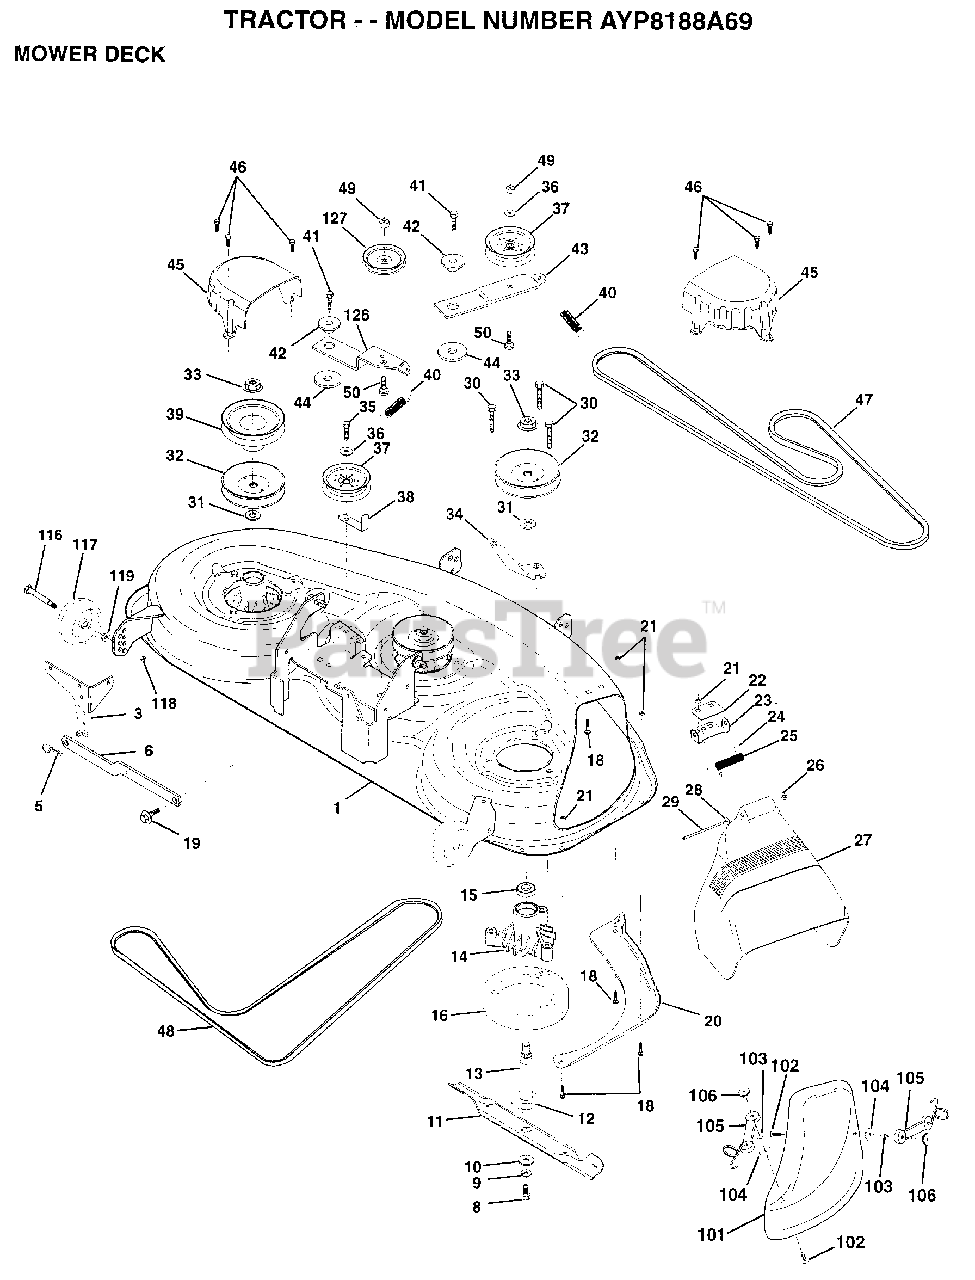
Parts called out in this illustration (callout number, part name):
3	BRKT.ASM.SW.44/50
8	BLADE BOLT
10	WASHER.HARD.BLADE
12	BEARING.BALL
13	SHAFT.ASM.W/BRNG
14	HOUSING.MAND.44.V
15	BEARING
16	STRIPPER RND MWR
18	BOLT
19	BOLT SHD 5/16-18
20	BAFFFLE.VORTEX.46
22	STIFFENER BRKT
23	DEFLECTOR BRKT
24	CAP-SLEEVE LT
26	NUT PUSH M
28	WASHER
29	HINGE ROD
31	WASHER
34	ANCHOR.SPRING.46
35	SCREW LT
36	WASHER
37	FLAT IDLER PULLEY
39	PULLEY.DRV.DCK.46
40	"SPRING.SEC.44""VEN"
41	SCREW
42	SPACER RETAINER
43	ARM.IDLER.DECK.46
44	HARDENED WASHER
45	COVER.MANDREL.46
46	SCREW.1/4-20X5/8
47	BELT-V.SEC.46.KEL
48	BELT.MWR.PRM.85.4
50	BOLT.3/8-16X1.50
101	COVER.MULCHING.
102	SCREW
103	LOCKWASHER
104	WASHER #10
106	WELDNUT
116	BOLT.SHOULDER
117	WHEEL GAGE DONUT
118	LOCKNUT
119	WASHER
126	ARM.IDLER.PRIM.46
127	PULLEY.IDLER.4.25
